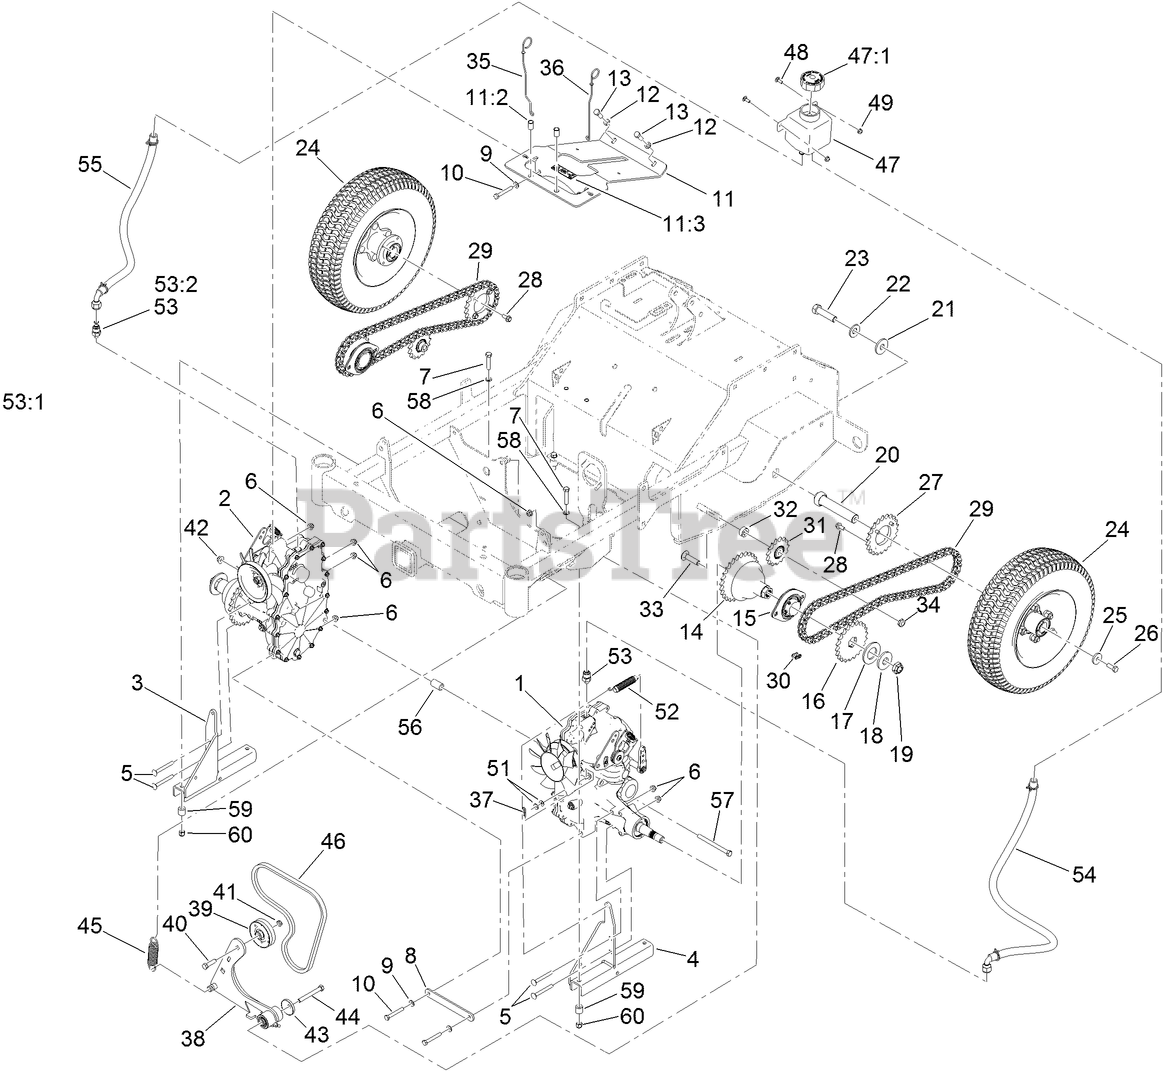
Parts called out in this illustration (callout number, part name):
1	HYDRO-ZT3100, LH
2	HYDRO-ZT3100, RH
3	MOUNT-HYDRO, RH
4	MOUNT-HYDRO, LH
5	SCREW-CARR
6	NUT-HF, NI
7	SCREW-HH
8	CROSSMEMBER-TRANSMISSION
9	WASHER-PLAIN
10	SCREW-HH
11	SUPPORT-COVER
11:2	NUT-CLINCH
11:3	DECAL-DANGER
12	WASHER-LOCK
13	SCREW-HH
14	HUB-BELL
15	BEARING-FLANGED
16	SPROCKET
17	WASHER-SPACER
18	WASHER-BELLEVILLE
19	NUT-LOCK
20	AXLE-WHEEL, DRIVE
21	WASHER-SPACER
22	WASHER-BELLEVILLE
23	SCREW-HH
24	WHEEL AND TIRE ASM
25	WASHER-FLAT
26	SCREW-HH, LOCK
27	SPROCKET
28	SCREW-HHF
29	CHAIN-ROLLER
30	LINK-CONNECTING
31	SPROCKET-IDLER, 15T
32	SPACER
33	SCREW-HH
34	NUT-HEX
35	ROD-BYPASS, LH
36	ROD-BYPASS, RH
38	IDLER ARM ASM
39	PULLEY-IDLER
40	SCREW-HH
42	NUT-HF, NI
43	GUARD-TOP
44	SCREW-HH
45	SPRING-EXTENSION
46	BELT-V, COGGED
47	TANK-HYD
47:1	CAP-RESERVOIR, HYD
48	BOLT-CARR
49	NUT-HF
51	WASHER
52	SPRING-EXTENSION
53	FITTING-STRAIGHT
53:1	O-RING
53:2	O-RING
54	HOSE ASM
55	HOSE ASM
56	SPACER
57	SCREW-HH
58	SPACER-BRAKE, PARKING
59	SPACER
60	NUT-LOCK
